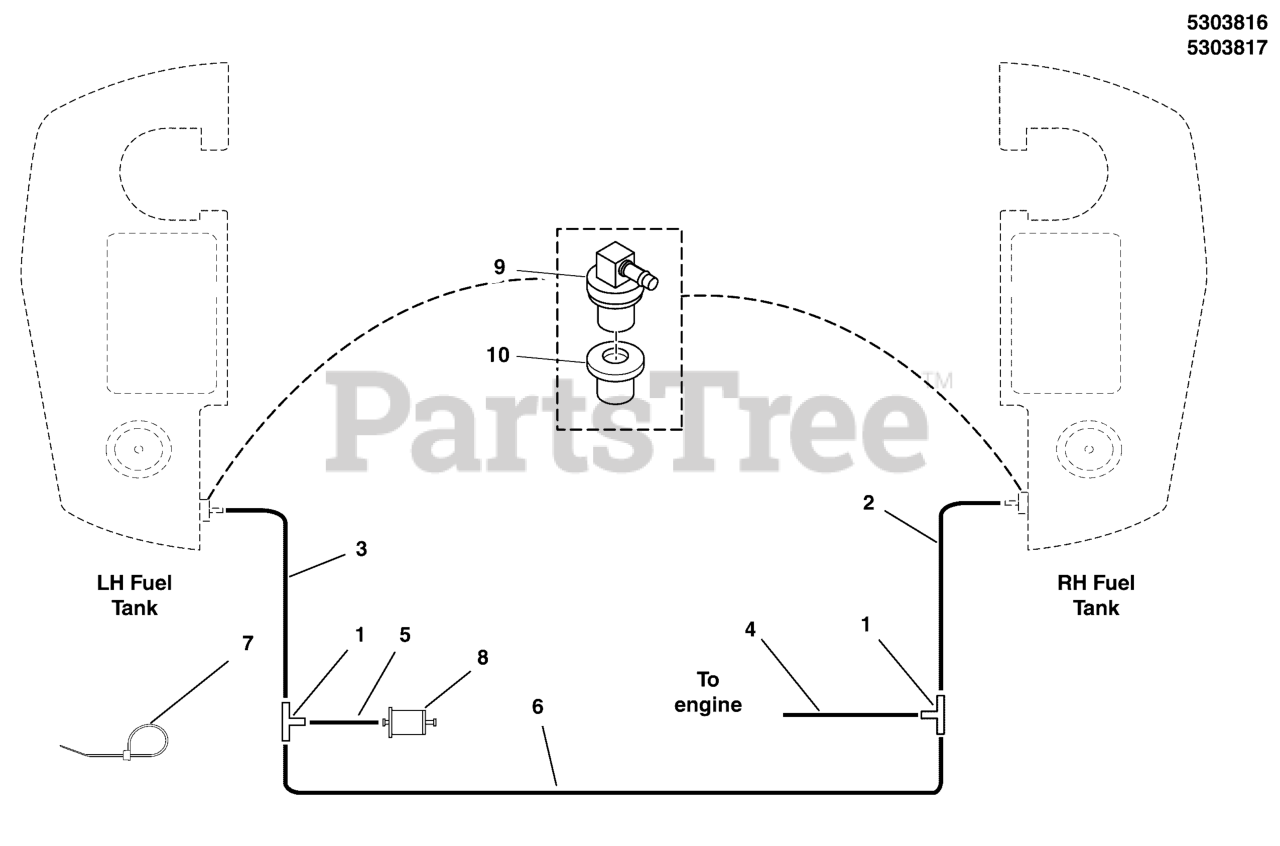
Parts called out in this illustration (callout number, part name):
1	FITTING, 3/16" TEE, BARB TYPE, HDPE
2	HOSE, VAPOR, 5MM ID, 16.50 LG
3	HOSE, VAPOR, 5MM ID, 33.00 LG
4	HOSE, VAPOR, 5MM ID, 8.00 LG
5	HOSE, VAPOR, 5MM ID, 2.00 LG
6	HOSE, VAPOR, 5MM ID, 15.00 LG
7	TIE,SELF-LOCKING, 6"
8	FILTER, FUEL
9	REMOTE VENT ASSEMBLY
10	GROMMET
